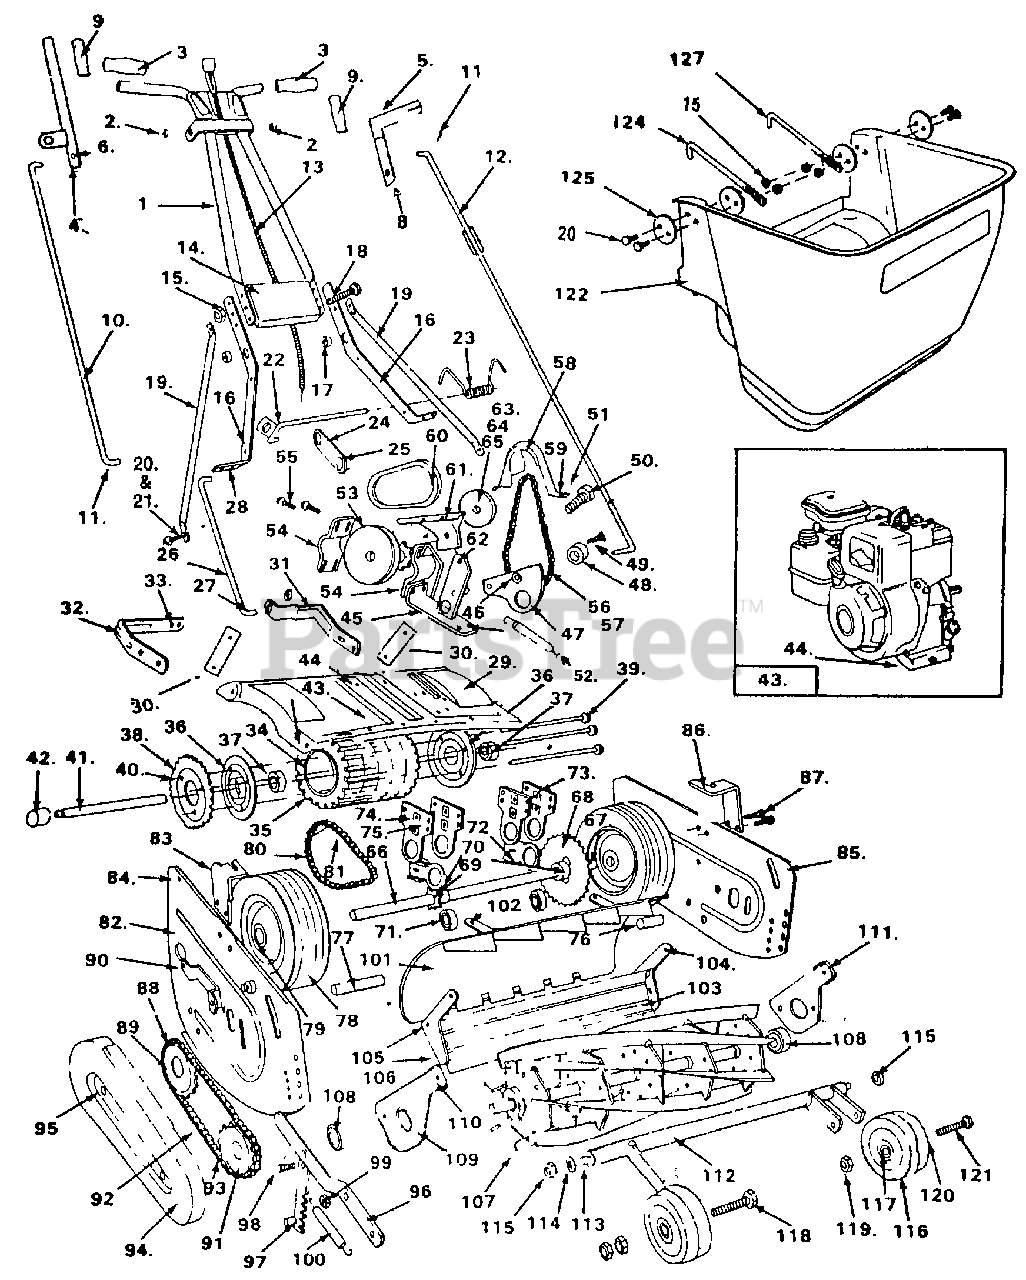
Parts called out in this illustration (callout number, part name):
1	HANDLE W/BEARING
2	HANDLE BEARINGS ONLY
3	HANDLE GRIPS (2 REQ.)
4	DRIVE CONTROL LEVER
5	CLUTCH CONTROL LEVER
6	BOLT 7/16" x 1-1/4" (2 REQ.) L & R
8	LOCK NUTS 7/16"-14 (2) L & R
9	DRIVE & CLUTCH LEVER GRIPS
10	DRIVE CONTROL ROD
11	COTTER PINS 1/8" x 1/2" (3 REQ.)
12	CLUTCH CONTROL ROD
13	THROTTLE CONTROL ASSEMBLY
14	HANDLE BRACE PLATE
15	1/4"-28 NUTS (6 REQ.)
16	LOWER HANDLE W/BEARING (2 REQ.)
17	BEARINGS ONLY
18	1/4"-28 X 7/8" BOLTS (6 REQ.)
19	HANDLE BRACE (2 REQ.) L & R
20	1/4"-28 X 5/8" BOLT (2 REQ.) L & R
21	1/4"-28 NUTS (2 REQ.) L& R
22	DRIVE PIVOT ROD
23	DRIVE PIVOT SPRING
24	DRIVE PIVOT ARM
25	SET SCREW 3/8"-16 X 1/2" SQUARE HEAD
26	LOWER DRIVE CONTROL ROD
27	COTTER PIN 1/8" X 1/2"
28	5/16"-18 X 3/4" BOLTS (4 REQ.) L & R
30	HANDLE BRACKETS (2 REQ.)
31	ROLLER SUPPORT BRACKET WITH BEARING
32	ROLLER SUPPORT BRACKET
33	5/16"-18 X 1/2" (2 REQ.)
34	ROLLER DRIVE TUBE
35	ROLLER DRIVE TIRES (5 REQ.)
36	ROLLER END CAPS (2 REQ.)
37	END CAP BEARINGS (2 REQ.)
38	ROLLER DRIVE SPROCKET (30 TEETH)
39	ROLLER DRIVE BOLTS (3 REQ.)
40	1/4"-28 DRIVE NUTS (3 REQ.)
41	ROLLER DRIVE SHAFT
43	ENGINE, 3 HP MODEL 80202-1676-02
44	5/16" X 24 X 1-1/2" BOLTS (4 REQ.)
45	MAIN CLUTCH BODY
46	CLUTCH BEARING
47	BELT IDLER ARM
48	IDLER BEARING (CONCAVE)
49	3/8"-16 X 1/2" FLAT HEAD PHILLIPS HEAD SCREW
50	7/16"-14 X 1-1/4" BOLT
51	WASHER 7/16"
52	CLUTCH SPRING/W SPRING PLATE
53	JACK SHAFT WITH PULLEY & SPROCKET
54	JACK SHAFT HOUSING (2 REQ.)
55	5/16"-18 X 3/4" BOLTS (4 REQ.)
56	CLUTCH DRIVE CHAIN - NO. 41 X 44 PITCH
57	CONNECTING LINK FOR NO. 41 CHAIN
58	CLUTCH CHAIN GUARD
59	5/16"-18 X 1/2" BOLT
60	CLUTCH BELT
61	BELT GUARD
62	5/16"-18 X 3/8" BOLT
63	ENGINE PULLEY
64	KEY FOR ENGINE PULLEY SHAFT 3/16" X 3/16" X 5/8"
65	ALLEN SET SCREW 5/16"-24 X 5/16"
66	REAR AXLE SHAFT
67	RETAINER RING
68	SPROCKET (30 TEETH WITH HUB)
69	SPROCKET (8 TEETH WITH HUB)
70	SET SCREWS 7/16"-20 X 7/16" HALF DOG (3 REQ.)
71	AXLE SUPPORT BEARING (2 REQ.)
72	ROLLER BRACKET SUPPORTS (2 REQ.)
73	AXLE HANGERS (4 REQ.)
74	HANGER BOLTS 5/16"-24 X 7/8" (8 REQ.)
75	5/16"-24 NUTS (8 REQ.)
76	SPACER 1-1/16"
77	SPACER 2-3/16"
78	REAR WHEELS WITH BEARINGS (2 REQ.)
79	REAR WHEEL BEARINGS WITH FLANGE (4 REQ.)
80	ROLLER DRIVE CHAIN NO. 41-36 PITCH
81	CONNECTING LINK NO. 41
82	SIDE PLATE WITH CHAIN GUARD BRACKET
83	CATCHER HOOK BRACKET
84	5/16"-18 X 3/4" (4 REQ.)
85	SIDE PLATE
86	CATCHER HOOK BRACKET
87	5/16"-18 X 3/4" (4 REQ.)
88	SPROCKET (17 TEETH)
89	SET SCREWS 7/16"-20 X 7/16" HALF DOG (4 REQ.)
90	5/16"-18 X 1/2" BOLTS (2 REQ.)
91	SPROCKET (13 TEETH)
92	REAL DRIVE CHAIN NO. 41-46 PITCH
93	CONNECTING LINK NO. 41
94	CHAIN GUARD
95	USE PART #1033
96	HEIGHT ADJUSTMENT LEVER
97	HEIGHT ADJUSTMENT NOTCHED BRACKET
98	SAME AS 1028
99	SPACER BUSHING
100	HEIGHT ADJUSTMENT SPRING
101	SHIELD ASSEMBLY HARDWARE
102	5/16"-18 X 1/2" BOLTS (2 REQ.)
103	BED KNIFE
104	SAME AS 1028
105	TAPERED BOLTS 5/16"-18 X 5/8" (6 REQ.)
106	BUSHING FOR TAPERED BOLT (6 REQ.)
107	REEL ASSEMBLY 6 BLADE
108	REEL BEARINGS (2 REQ.)
109	REEL BEARING RETAINER
110	SAME AS 1033
111	REEL BEARING RETAINER
112	FRONT WHEEL ASSEMBLY BAR
113	TIE ROD
114	PLASTIC WASHER
115	7/16"-14 NUTS (2 REQ.)
116	FRONT WHEELS WITH BEARINGS
117	FRONT WHEEL BEARINGS (2 REQ.)
118	7/16"-14 X 3-1/2" BOLT
119	7/16"-14 NUTS (3 REQ.)
120	7/16" FLAT WASHER
121	7/16"-14 X 3-1/4" BOLT
122	PLASTIC GRASS CATCHER
124	CATCHER HOOK
127	CATCHER HOOK
